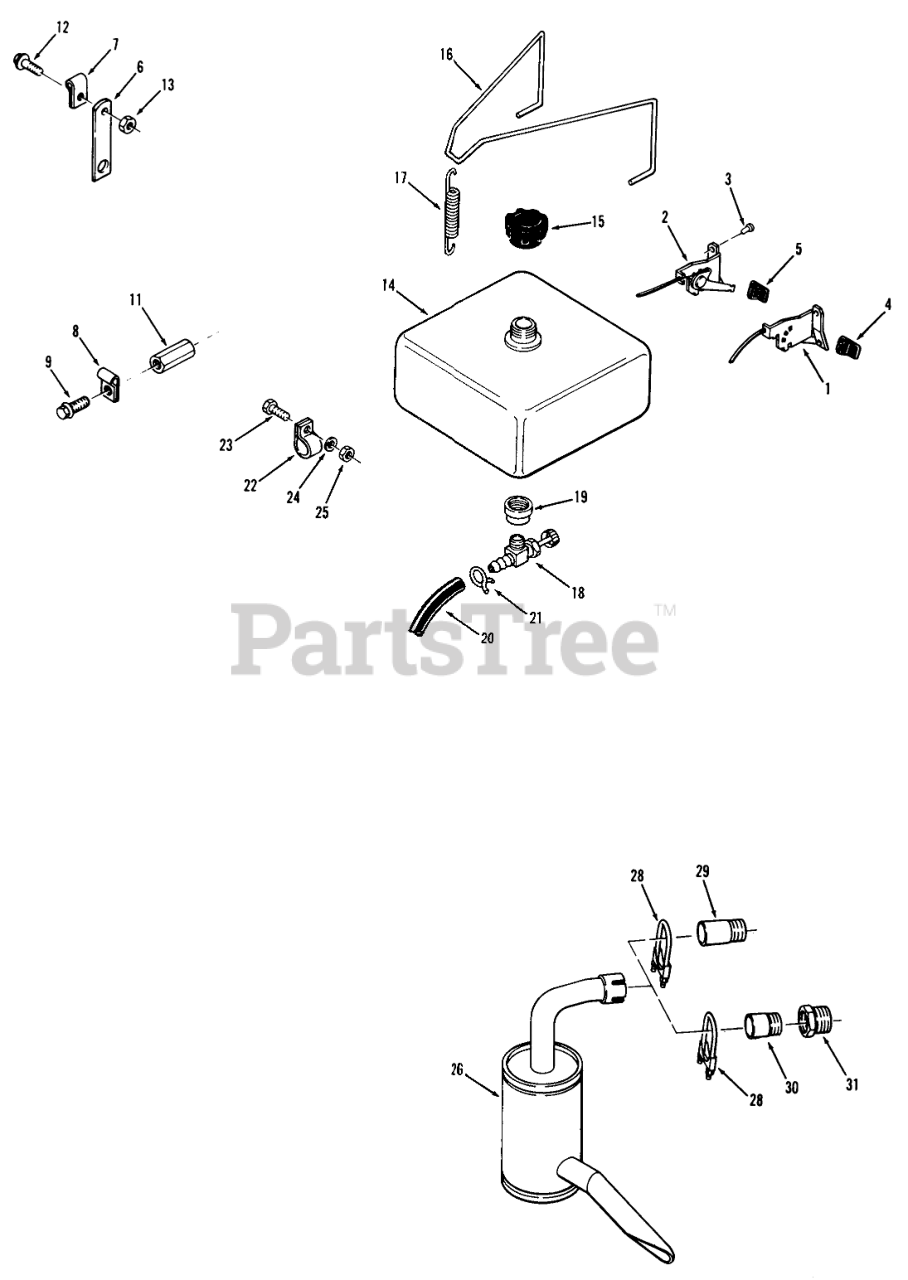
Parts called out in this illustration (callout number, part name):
1	Choke Control
2	THROTTLE CONTROL
3	RIVET-4
4	KNOB-CHOKE
5	KNOB-THROTTLE
6	Strap
7	THROTTLE CONTROL CLP
8	Clip
9	Screw
11	Special Nut
12	Screw
13	Nut
14	ASSY-FUEL TANK
15	Cap
16	HOLD DOWN WIRE
17	CLUTCH SPRING
18	VALVE-FUEL
19	BUSHING
20	Fuel Line
21	Clamp
22	CLAMP-HOSE
23	Bolt
24	WASHER 5/16 SAE
25	Nut
26	Muffler
28	ASSY-MUFFLER CLAMP
29	NIPPLE
30	NIPPLE- 1X2 SPECIAL
31	REDUCER 1 1/4-1
